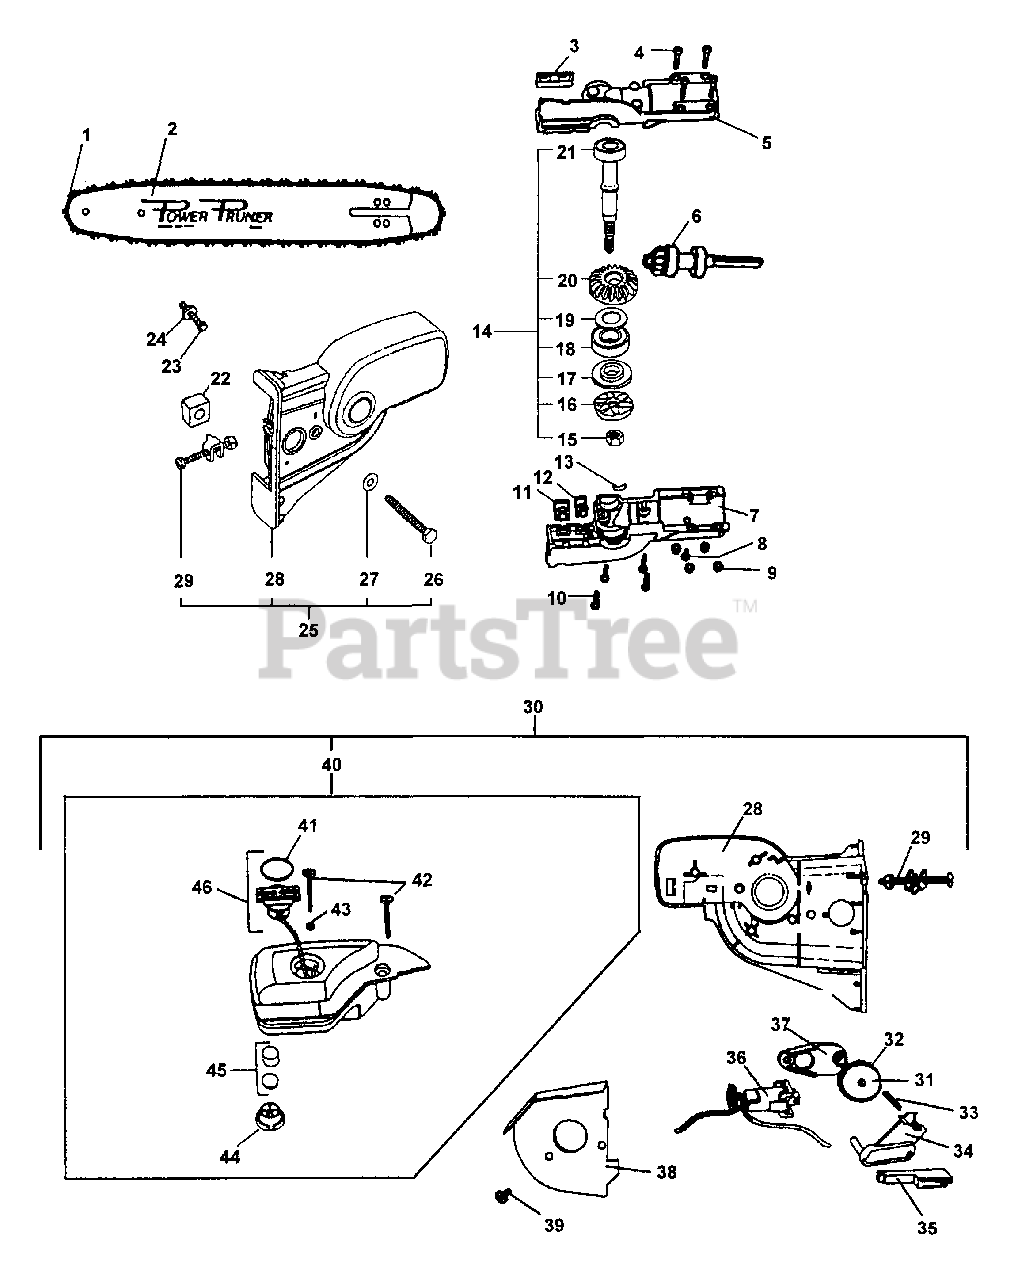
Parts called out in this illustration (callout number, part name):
1	SAW CHAIN - 12" (30cm)
2	GUIDE BAR - 12" (30cm)
3	BRACKET, GUIDE BAR
4	SCREW - 10-24 X 1-1/4"
5	CASE, GEAR - UPPER
6	SHAFT GEAR ASSY
7	CASE, GEAR - LOWER
8	SCREW
9	LOCKNUT - 10-24
10	SCREW - 10-24 X 7/8"
11	SPACER
14	GEAR SHAFT ASSY
16	SPROCKET, DRIVE
17	SPACER, SPROCKET
18	BEARING, BALL - 6001 DDU
20	GEAR - BEVEL
21	DRIVESHAFT SPROCKET ASSY
22	SPACER
23	SCREW - 1/4-20 X 1-3/4"
25	OILER COVER ASSY
26	BOLT - 1/4-20 X 2-1/4"
28	COVER, OIL PUMP
29	TENSIONER KIT
30	AUTO-OILER ASSY
31	CAM, OIL PUMP
34	LINK, OILER IDLER
35	PIPE, OIL OUTLET
36	AUTO-OILER ASSY
37	LINK, OILER DRIVE
40	OIL TANK ASSY
44	HOUSING, OIL FILTER
45	OIL FILTER ASSY
46	CAP ASSY
